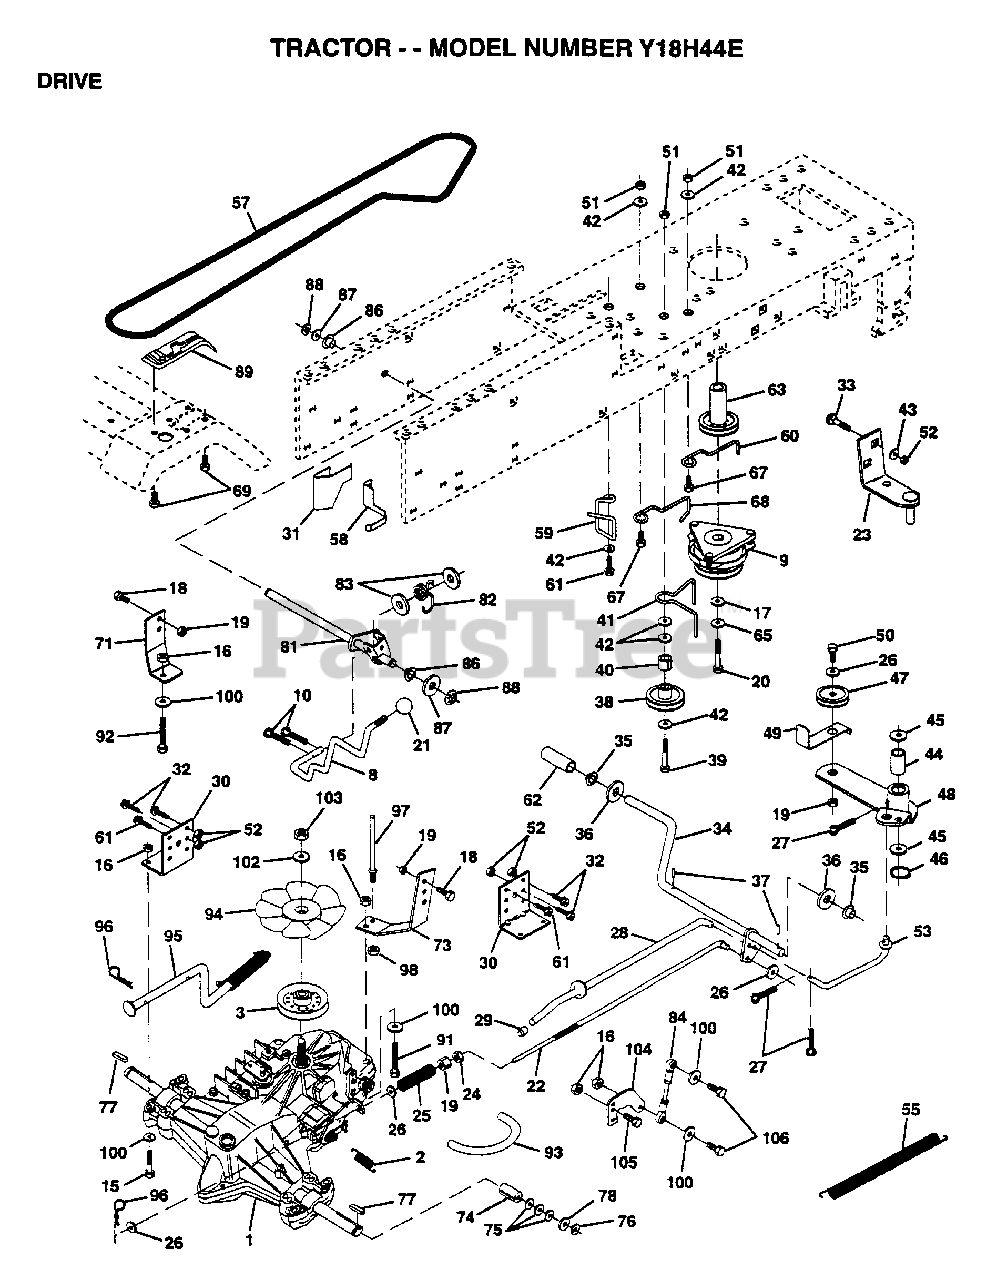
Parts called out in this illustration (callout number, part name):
2	SPRING RET BRAKE
3	PULLEY.TRANSAXLE
8	ROD SHIFT FEND YT
10	PIN COTTER 1/8
15	BOLT HEX
16	NUT
17	WASHER
18	BOLT
19	NUT
21	KNOB.DUCKHEAD.1/2
22	ROD.BRAKE.HYDRO.
23	BRACKET.ASM.MTG
24	NUT
25	SPRING ROD LT
26	WASHER
27	COTTER PIN
28	ROD.BRAKE.PARK.LT
29	PLUNGER CAP T
30	TRANSAXLE MTG BKT
31	"KEEPER,BELT LH T"
32	BOLT
33	BOLT
36	NYLON BEARING
36	WASHER LT
38	PULLEY.IDLER.FLAT
39	BOLT
40	SPACER T
41	BELT KEEPER LT
42	WASHER
43	WASHER T
44	"LY, BEARING"
45	WASHER LT
46	KLIP RING
48	ARM IDLER
49	RETAIN BELT
53	"LINK, CLUTCH T"
55	"SPRING, RETURN LT"
57	"BELT.GD DRV 82"""
58	KEEPER BELT LH
59	KEEPER BELT CNTSP
60	KEEPER BELT ENGLH
61	SCREW
62	PEDAL COVER T
63	PULLEY CLU ELEC
65	LOCKWASHER
67	BOLT
68	"KEEPER,BLT ENG LT"
69	SCREW HEXWSH H-L
71	STRAP TORQ LH HYD
73	STRAP TORQ RH HYD
74	SPACER SPLIT
75	WASHER
76	E-RING LT
77	SQUARE KEY
78	WASHER
82	"SPRING,TORSION"
83	WASHER
84	ROD.TIE.BALL.4.75
86	BUSHING
87	WASHER D
88	KLIP RING
92	HEX BOLT
93	"LINE FUEL HYD 4"""
94	"FAN 7"" HYDRO"
96	RETAINER M
97	BOLT KEEPER RH
98	NUT
100	WASHER M
102	WASHER BELLEVILLE
103	NUT NYLON 1/2-20
104	ARM CONTROL HYDRO
105	SCREW CAP 5/16-18
106	BOLT
